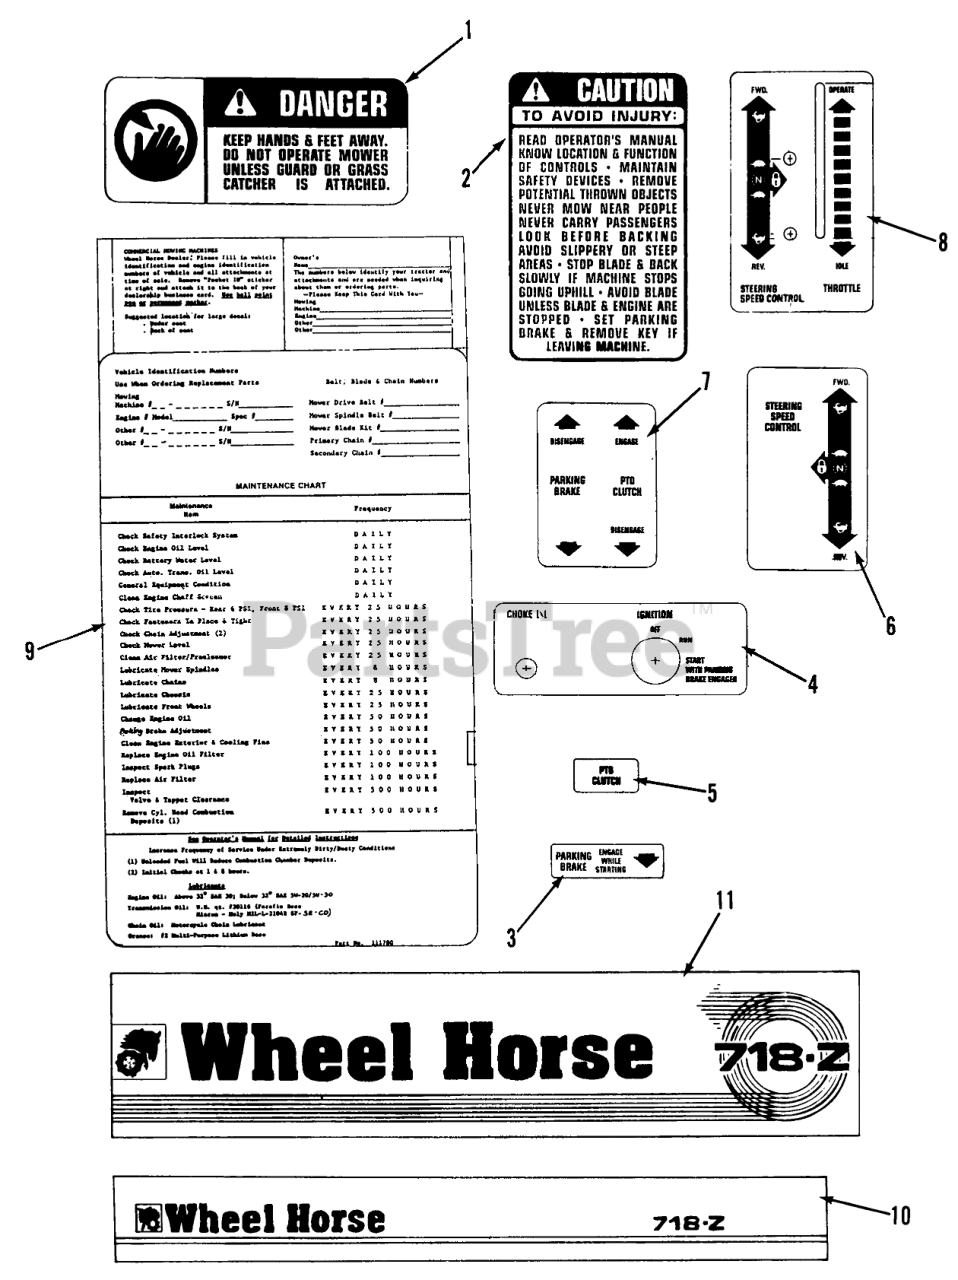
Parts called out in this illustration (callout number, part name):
1	Danger Decal
2	DECAL CAUTION
3	DECAL-PARKING BRAKE
4	DECAL-CHOKE/IGNITION
5	Decal-PTO Clutch
6	Decal-SpeedControl
7	DECAL-PARKING BRAKE
8	Decal-Steering/Throttle
9	Decal-Maintenance
10	DECAL-FRONT
11	DECAL-FENDER RH
